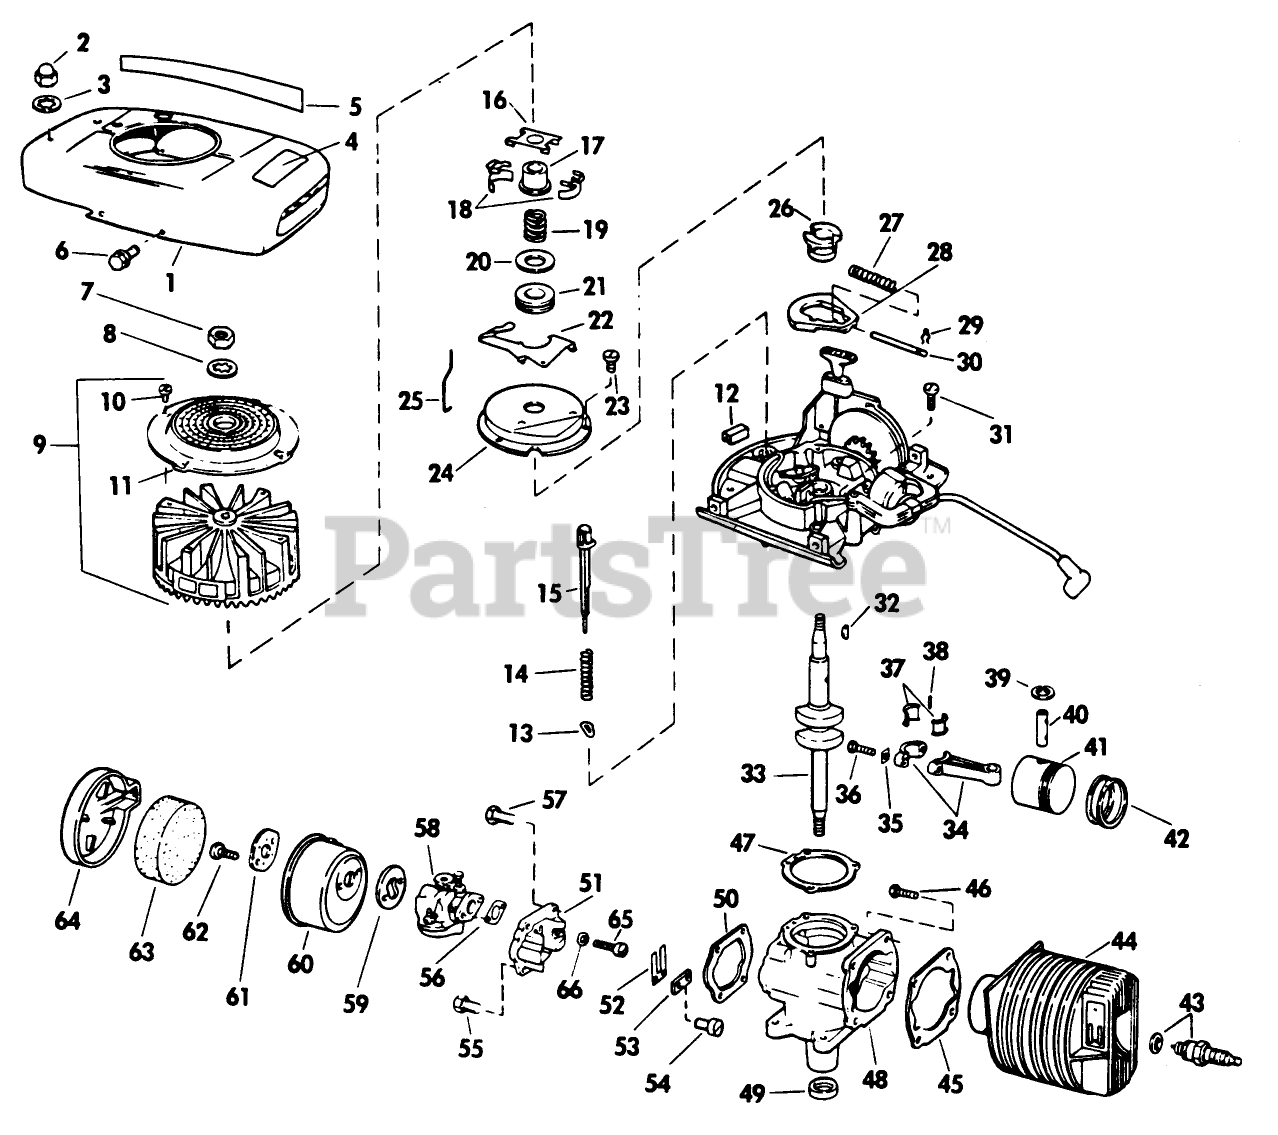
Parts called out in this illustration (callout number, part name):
2	PALNUT S
6	SCREW S
9	Flywheel Screen Assy.
10	SCREW F
14	SPRING S
17	COLLAR S
21	THRUST COLLAR S
22	LEVER-GOVERNOR S
23	SCREW S
24	DUST COVER S
26	SPARK ADV. S
27	SPARK ADV. SPRING S
28	FLYWEIGHT S
29	SPARK ADJ. SPRING
30	PIN,SPARK ADV. S
31	SCREW S
37	LINER ASM
39	RING-RETAINING
43	Spark Plug Gasket Champion CJ-14, .025" Gap
45	GASKET S
47	GASKET S
50	GASKET S
51	REED PLATE AY. S
53	PLATE-BACKUP, REED
55	SCREW S
56	GASKET S
57	SCREW S
59	GASKET S
62	SCREW S
63	AIR FIL.ELEM S
